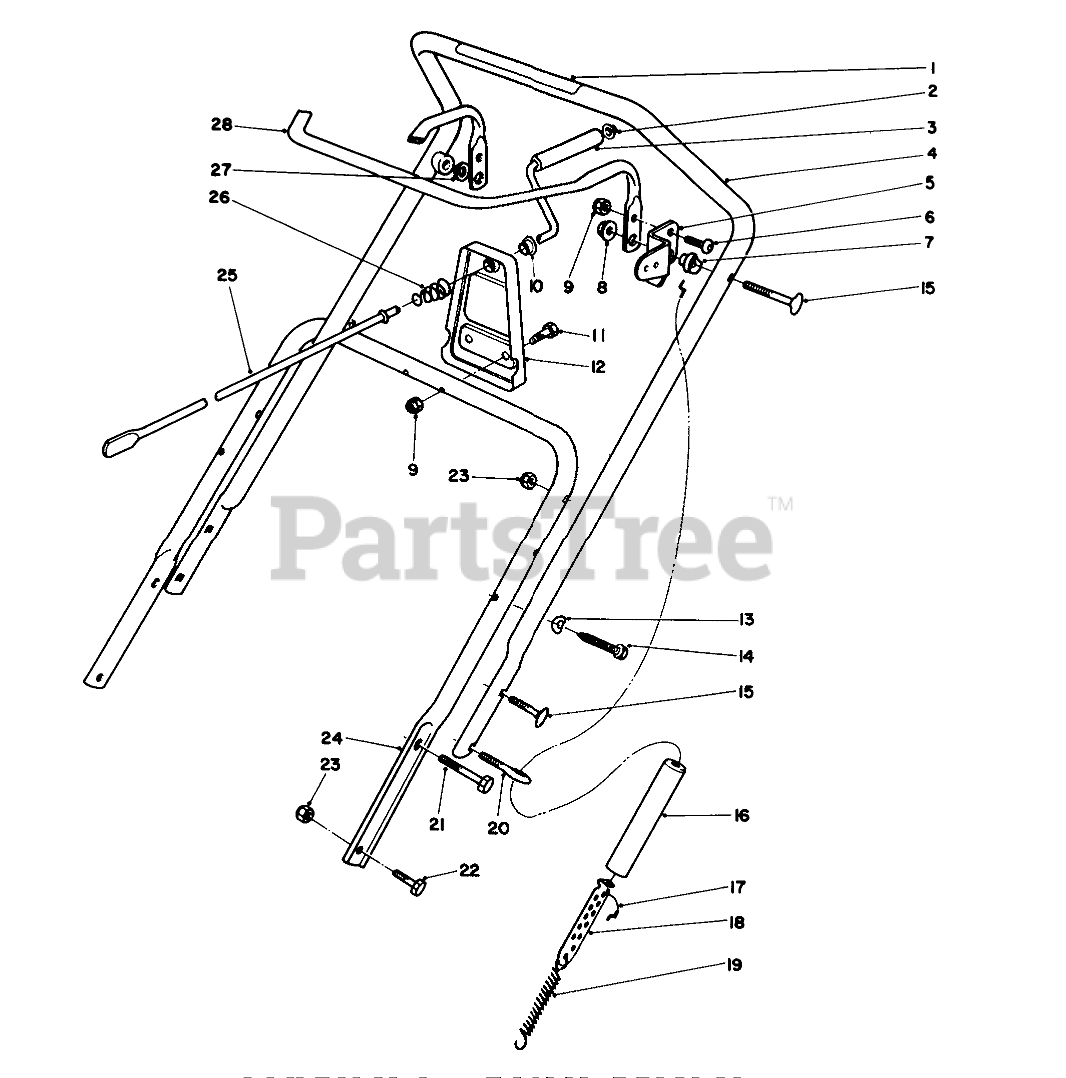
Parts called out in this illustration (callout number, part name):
1	DECAL - ROTOR DRIVE
2	RETAINER-PUSH ON
3	Grip-Rod
4	Upper Handle Assembly (Incl. ref. #1, Model 38185)
5	Arm-Clutch Cable
6	SCREW-HSBH
7	SPACER-BAR, CONTROL
8	NUT-LOCK, CAP
9	NUT-LOCK, NI
10	Bushing
11	SCREW-HH
12	Support-Crank
13	WASHER
14	SCREW
15	SCREW
16	COVER-SPRING
17	CABLE-CLUTCH
18	ADJUSTER-CABLE
19	SPRING-EXTENSION
20	BOLT-EYE
21	SCREW-HH
22	SCREW-HH
23	NUT-LOCK, NI
24	Handle-Lower (Model 38180)
25	ROD-CRANK, CHUTE
26	SPRING-COMPRESSION
27	WASHER
28	Bar-Control
